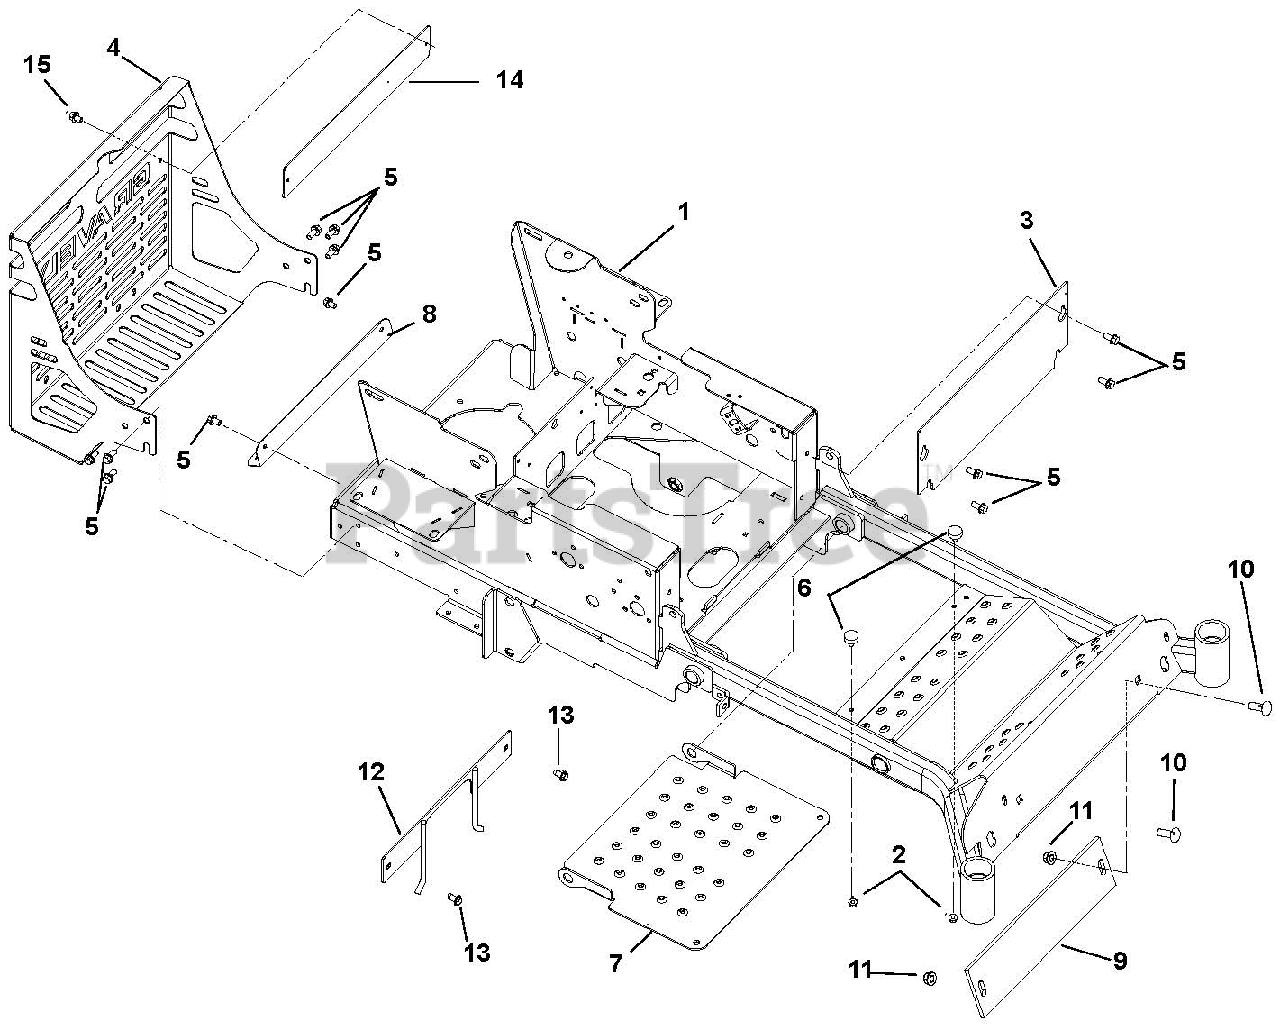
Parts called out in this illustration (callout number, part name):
1	Weldment, 44"HD Frame
2	Nut, Spin Lock Flange .312-18
3	Kick Plate
5	Screw, Tapping .38-16 x .75 Hex Washer Head
6	Bumper, Rubber
7	Panel, Inspection
8	Heat Shield
9	Counterweight CZ Front
10	Bolt, Round Head Square Neck .50-13 x 1.25 Grade 5
11	Nut .50-13 Nyloc Flange
12	Weldment, PTO Belt Finger
13	Screw, Tapping .38-16 x .75 Hex Washer Head Thread
14	Bumper Backing Plate
15	Screw, Tapping .25-20 x .50 Hex Washer Head
